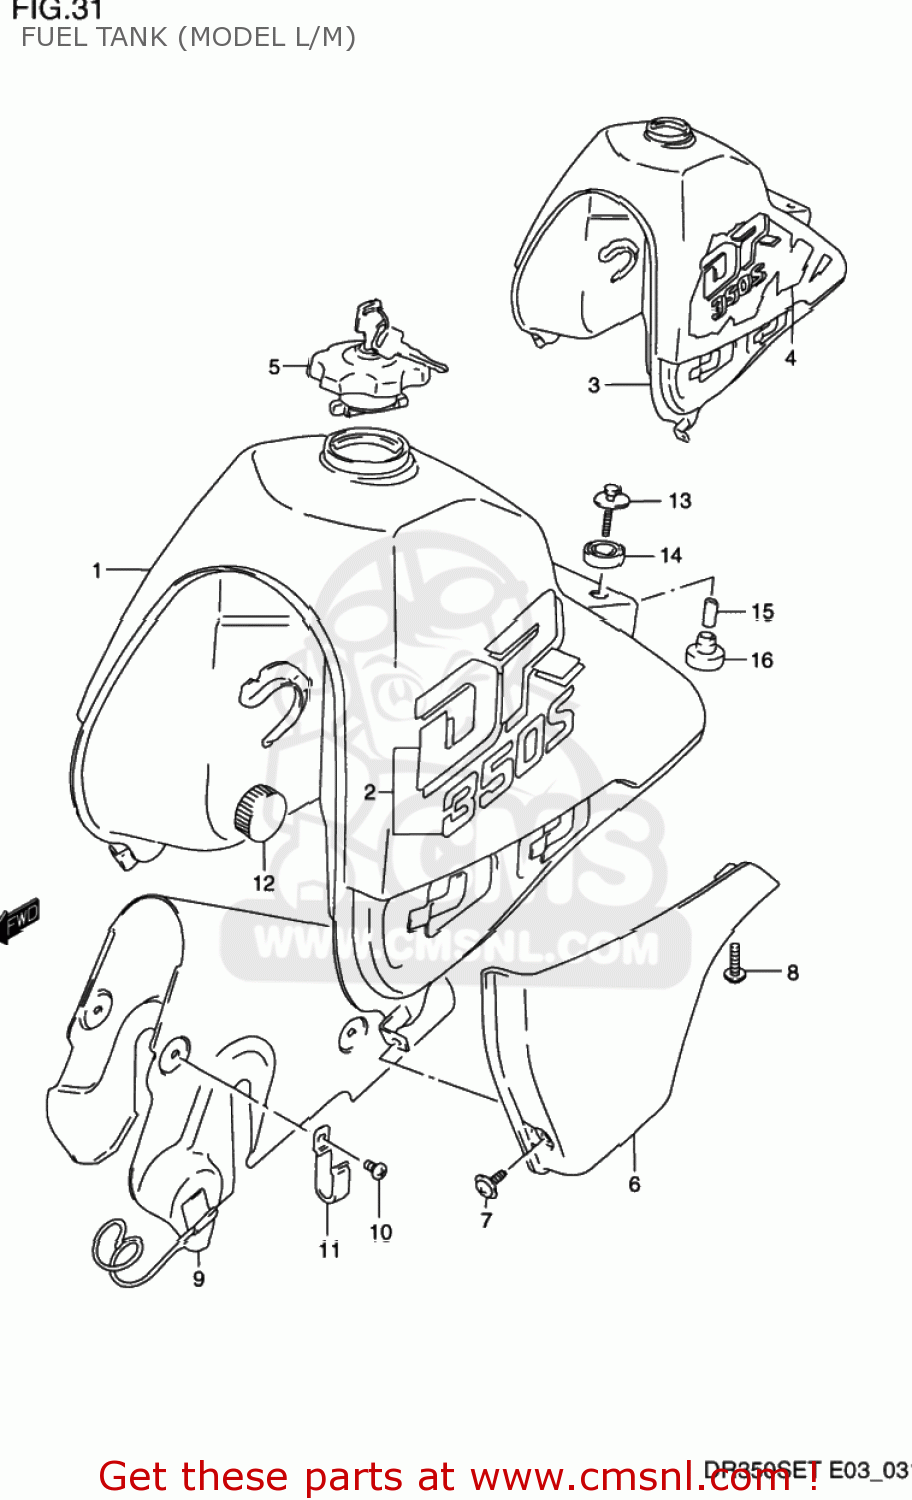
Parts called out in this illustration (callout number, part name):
1	TANK ASSEMBLY,FUEL
2	EMBLEM,FUEL TANK
3	TANK ASSEMBLY,FUEL
4	TAPE SET,FUEL TANK
5	CAP SET,FUEL TANK
6	COVER,FUEL TANK,R
7	SCREW
8	SCREW(6X12)
9	SHIELD,FUEL TANK
10	SCREW
11	CLAMP(L:65)
12	CUSHION
13	BOLT
14	CUSHION
15	SPACER
16	CUSHION
